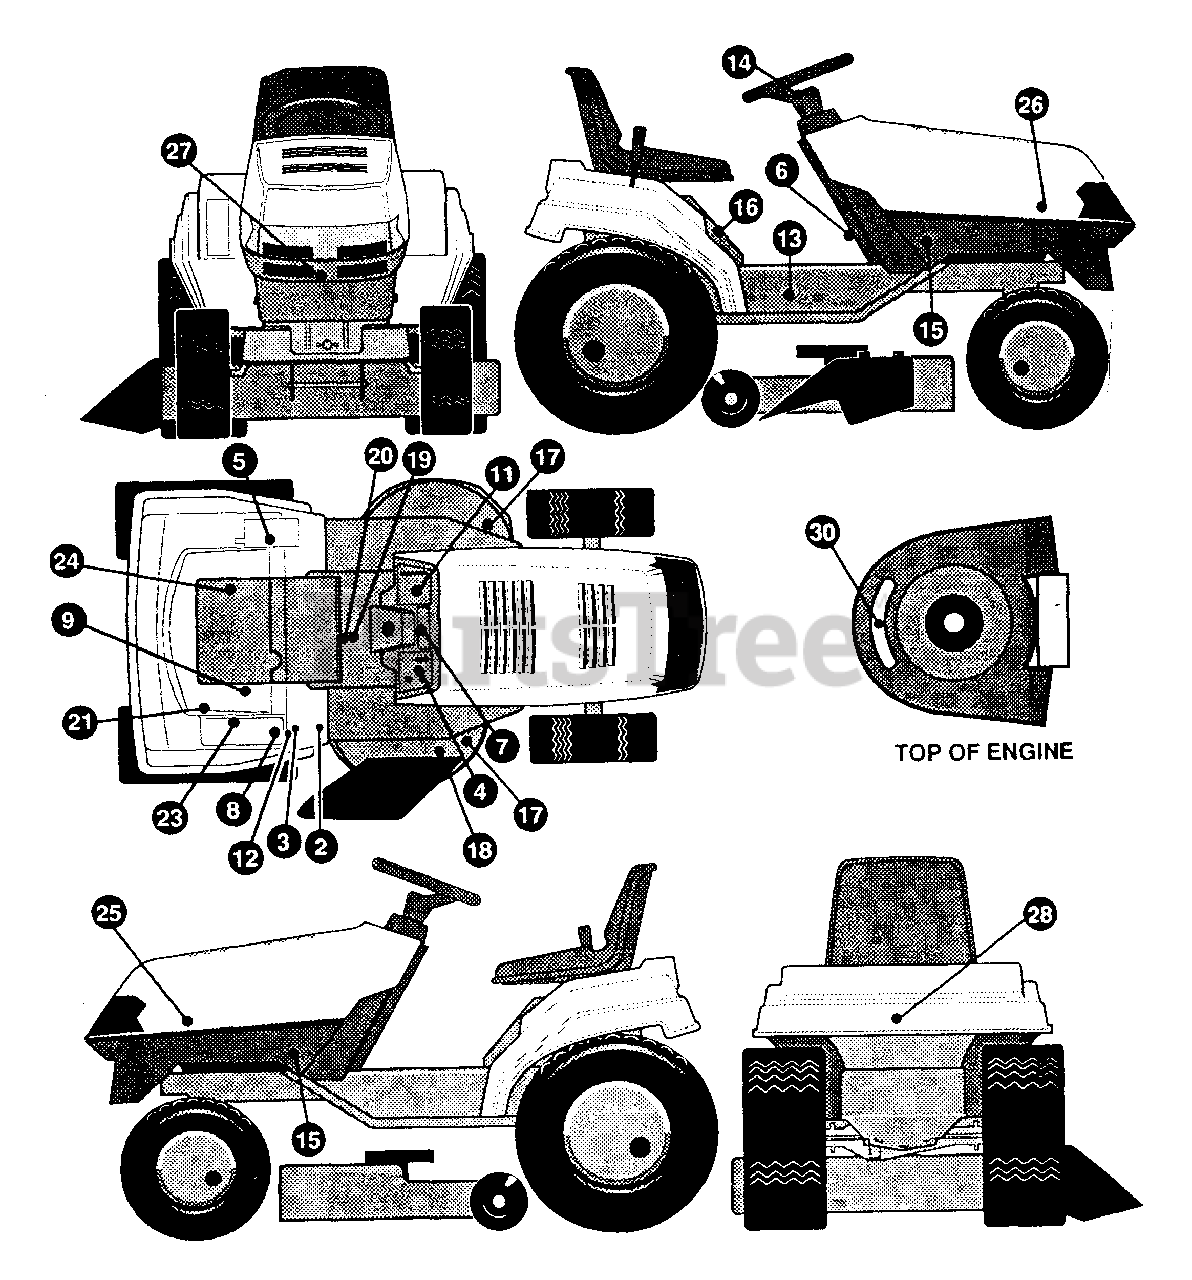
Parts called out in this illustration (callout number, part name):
1	REFERENCE ONLY
2	DECAL, CAUTION TRIANGLE EUROPE
3	DECAL, DANGER FRENCH, ENGLISH
4	DECAL, DASH RH ISO CH,HR LS IS
5	DECAL, HEIGHT E/C EXPORT
6	DECAL, PARK BRAKE EXPORT
7	DECAL, DASH OIL,FUEL,ASG NO CHG
8	DECAL, DEPRESS CL/BRAKE BLACK
9	DECAL, CERT .DE CONFORMITE 1994
11	DECAL, DASH LH ISO,AMM,E/CL,M/CH
12	DECAL, DANGER GERMAN
13	DECAL, DANGER CONS SIDE SWEDISH
14	DECAL, GUNSIGHT CENT 3 SPOKE
15	DECAL, WHEEL 4 STEER HUSQ. BUM
16	DECAL, LAWN TRACTOR SEAT SUPP
17	DECAL, WARN 11/LANG HANDS/FEET
18	DECAL, WARN DEFLECTOR SHIELD 11 LANG
19	DECAL, START INST CONS 11 LANG
20	DECAL, ENTER & EXIT 11/LANG
21	DECAL, 4WS PATENT NO. 5048853
22	REFERENCE ONLY
23	DECAL, MOTION HYDRO-EXPORT
24	DECAL, RELIEF VALVE OPERATION
25	DECAL, HOOD HUSQ HYDRO LH
26	DECAL, HOOD HUSQ HYDRO RH
27	DECAL, GRILLE HUSQVARNA
28	DECAL, REAR FENDER HUSQVARNA
